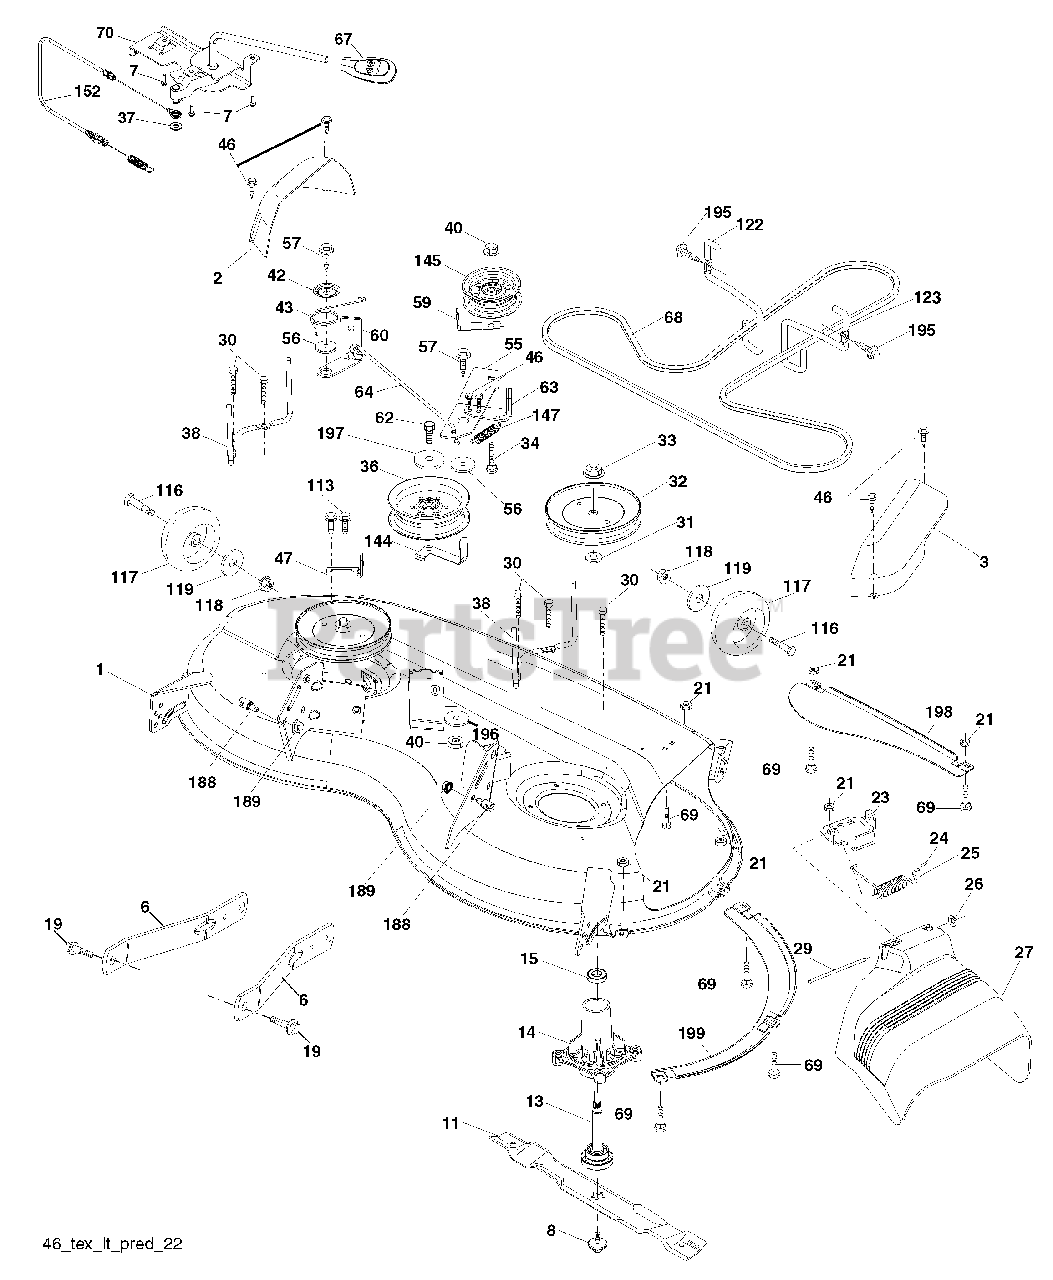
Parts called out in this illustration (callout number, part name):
1	Mower Housing
2	Cover Mandrel
3	Cover Mandrel
6	Arm Suspension
7	Screw 10 x 3/4 Single Hex
8	Bolt/Washer asm 7/16-20 unf
11	Blade Mower
13	Shaft Assembly, Mandrel
14	Housing, Mandrel
15	Bearing, Ball, Mandrel
19	Bolt, Shoulder
21	Nut
23	Bracket, Deflector
24	Cap, Sleeve
25	Spring, Torsion, Deflector
26	Nut, Push
27	Shield, Deflector
29	Rod, Hinge
30	Screw Thdrol Rolling Wsh Hd
31	Washer, Spacer
32	Pulley, Mandrel
33	Nut, Toplock, Flanged
34	Bolt Carr Sh. 3/8-16 x 1-1/2 Gr. 5
36	Pulley, Idler, Flat
37	Washer 13/32 x 13/16 x 16 Ga.
38	Keeper Belt LH Mandrel
40	Nut, Lock Flg. 3/8-16 unc
42	Spring Torsion Brake
43	Spring Torsion Retainer
46	Screw
47	Bracket Clutch Cable
55	Arm, Idler
56	Spacer, Retainer
57	Screw Hexwsh Thd 3/8-16 x 1
59	Guard, Tuv Idler (94)
60	Arm Brake Mower
62	Bolt Fin Hex 3/8-16 x 2-1/4 Gr. 5
63	Arm Brake Mower
64	Linkage Brake
67	Handle, Clutch Cable
68	V-Belt
69	Bolt
70	Clutch Asm. Manual
113	Screw 5/16-18
116	Bolt, Shoulder
117	Wheel, Gauge
118	Nut, Centerlock 3/8-16
119	Washer 3/8 x 7/8 x 14 Ga.
122	Keeper Belt Eng. LH
123	Keeper Belt Eng. RH
144	Keeper Belt
145	Pulley Idler
147	Spring Return
152	Cable Clutch Manual w/Spr.
188	Stud Fastener
189	Nut Lock Hex Flange
195	Screw Hexwsh Thdrol 3/8-16 x 3/4
196	Washer 13/32 x 2 x 10 Ga.
197	Washer 13/32 x 13/16 x 12 Ga.
198	Baffle Center Front
199	Baffle Front RH
199	Mandrel Assembly
199	Replacement Mower, Complete
